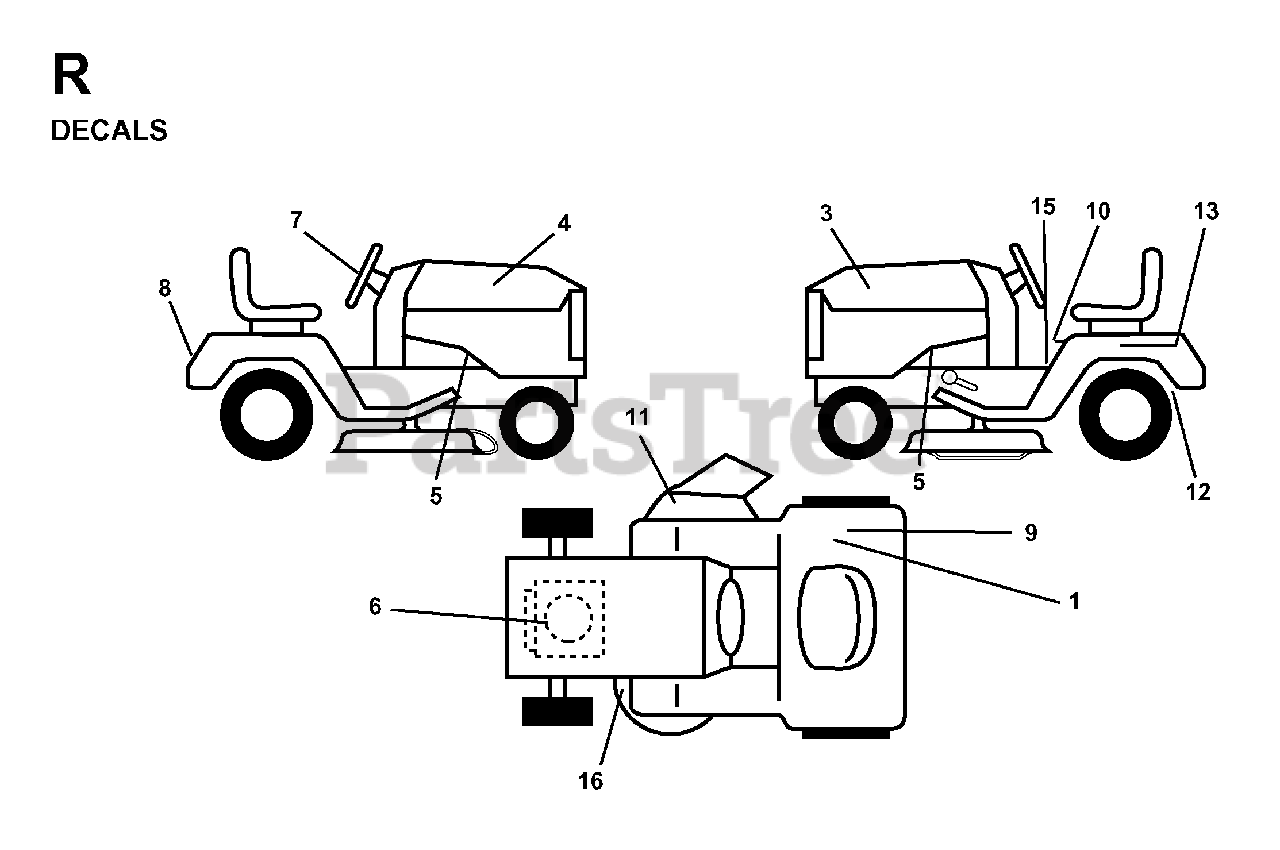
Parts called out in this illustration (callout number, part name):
1	DECAL EUROPE STANDARD CE
9	DECAL CERTIFICATION
10	DECAL READ OWNER'S MAN SYMS
11	DECAL MOWER CUT/FINGER
13	DECAL BTRY SYMBOLS
16	DECAL
